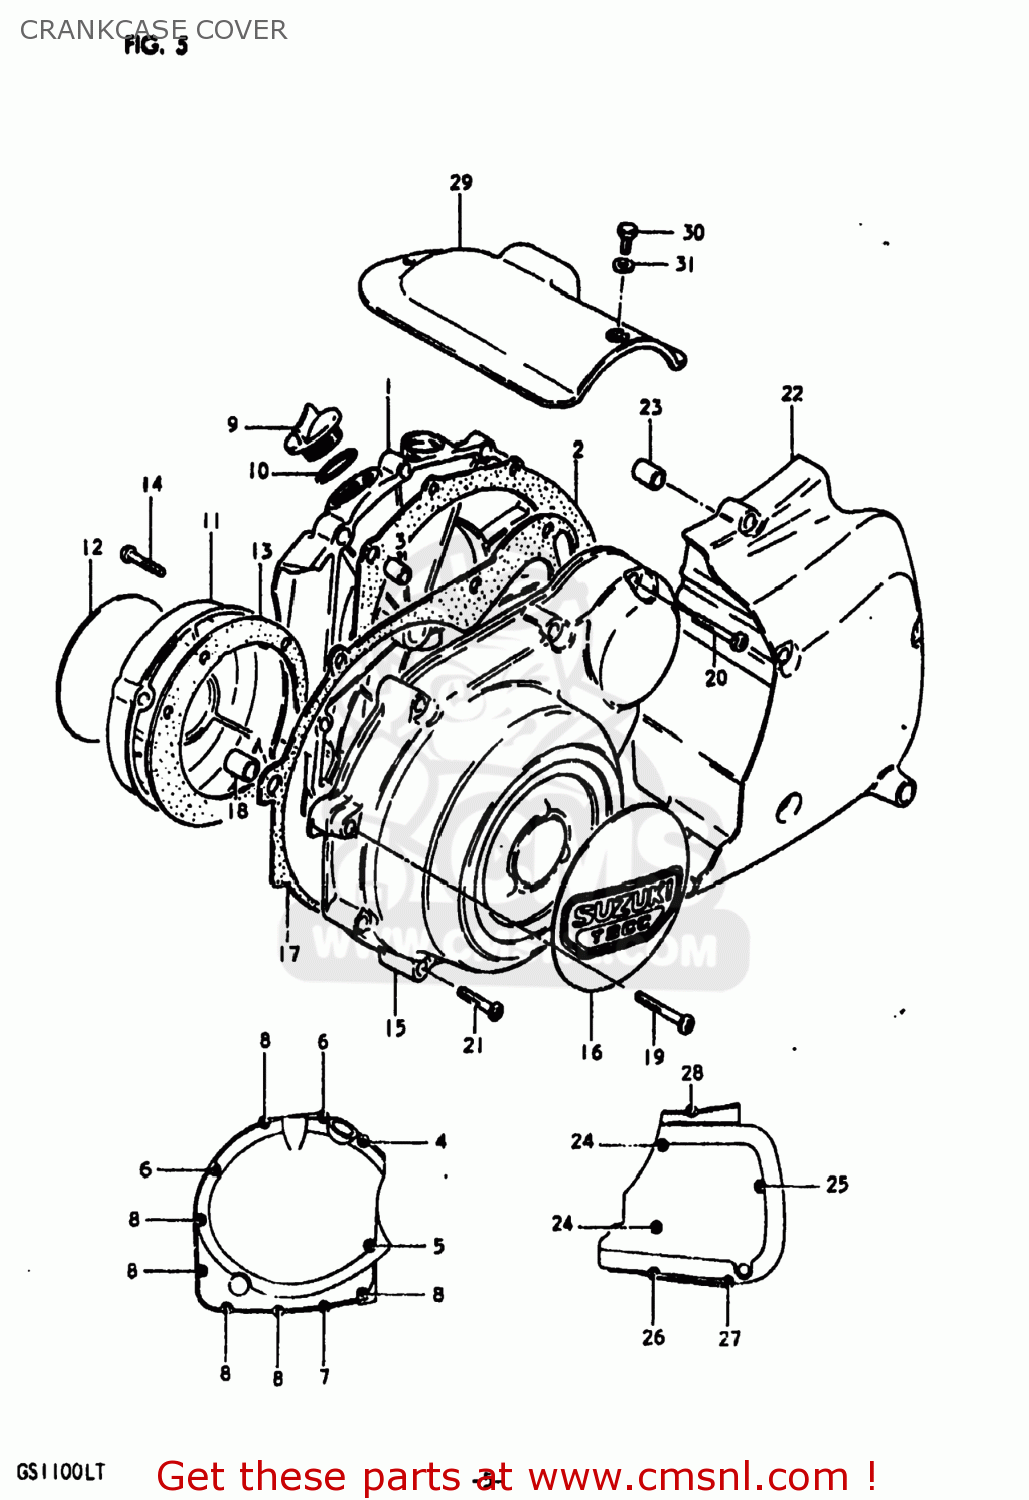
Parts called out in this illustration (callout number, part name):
1	COVER,CLUTCH
2	GASKET,CLUTCH COVER (MCA)
3	PIN
4	SCREW
5	SCREW (6X35)
6	SCREW 6X30
7	SCREW
8	SCREW
9	CAP
10	O RING(D:2.2,ID:32)
11	COVER,CONTACT BREAKER
12	EMBLEM
13	GASKET,CONTACT BREAKER COVER (NAS)
14	SCREW
15	COVER
16	EMBLEM,MAGNETO COVER
17	GASKET,MAGNETO COVER (MCA)
18	PIN
19	SCREW (6X45)
20	SCREW
21	SCREW 6X30
22	COVER,SPROCKET
23	PIN
24	SCREW (6*95)
25	SCREW 6X85
26	SCREW 6X70
27	SCREW
28	SCREW 6X30
29	COVER,STARTER MOTOR
30	BOLT
31	WASHER
